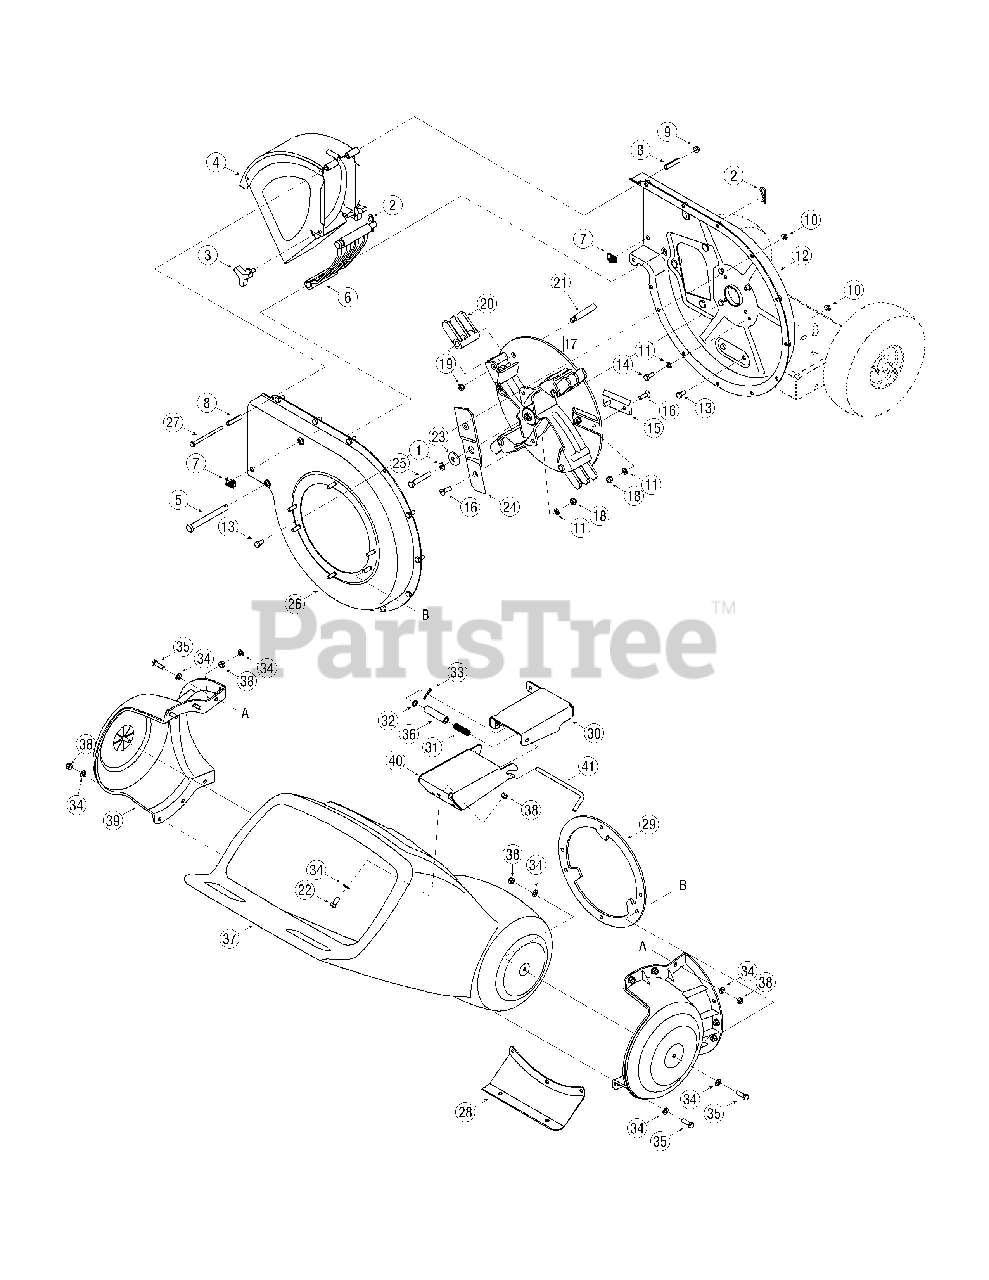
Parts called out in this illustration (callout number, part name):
1	Lock Washer, 3/8
2	Cotter Pin
3	Wing Knob 5/16-18
4	Chute Deflector Assembly
5	Clevis Pin
6	Shredder Screen
7	U-Nut 5/16-18
8	Spacer
9	Hex Lock Nut, 1/4-20
10	Hex Lock Nut 5/16-18
11	Lock Washer 5/16
12	Inner Impeller Housing Assembly
13	Hex Cap Screw 5/16-18 x.625
14	Hex Cap Screw 5/16-24 x .75
15	Chipper Blade
16	Hex Cap Screw 5/16-24 x 1.0
17	Impeller Assembly
18	Hex Lock Nut 5/16-24
19	Nut, Jam Lock, 3/8-16
20	Flail Blade
21	Shoulder Pin, .5 x 2.625
22	Hex Cap Screw 5/16-18 x .75
23	Flat Washer 3/8 x 1.25
24	Shredder Blade
25	Hex Cap Screw 3/8-24 x 2.25
26	Outer Impeller Housing Assembly
27	Hex Cap Screw 1/4-20 x 3.75
28	Front Support Bracket
29	Shredder Plate
30	Rear Hopper Bracket Assembly
31	Compression Spring 1.75
32	Flat Washer
33	Cotter Pin
34	Flat Washer.330 ID x .630 OD
35	Hex Cap Screw 5/16-18 x 1.0
36	Spacer, .375 ID x 2.50 LG
37	Hopper Assembly
38	Hex Lock Nut 5/16-18
39	Hopper Collar
40	Front Hopper Bracket Assembly
41	Lock Rod
